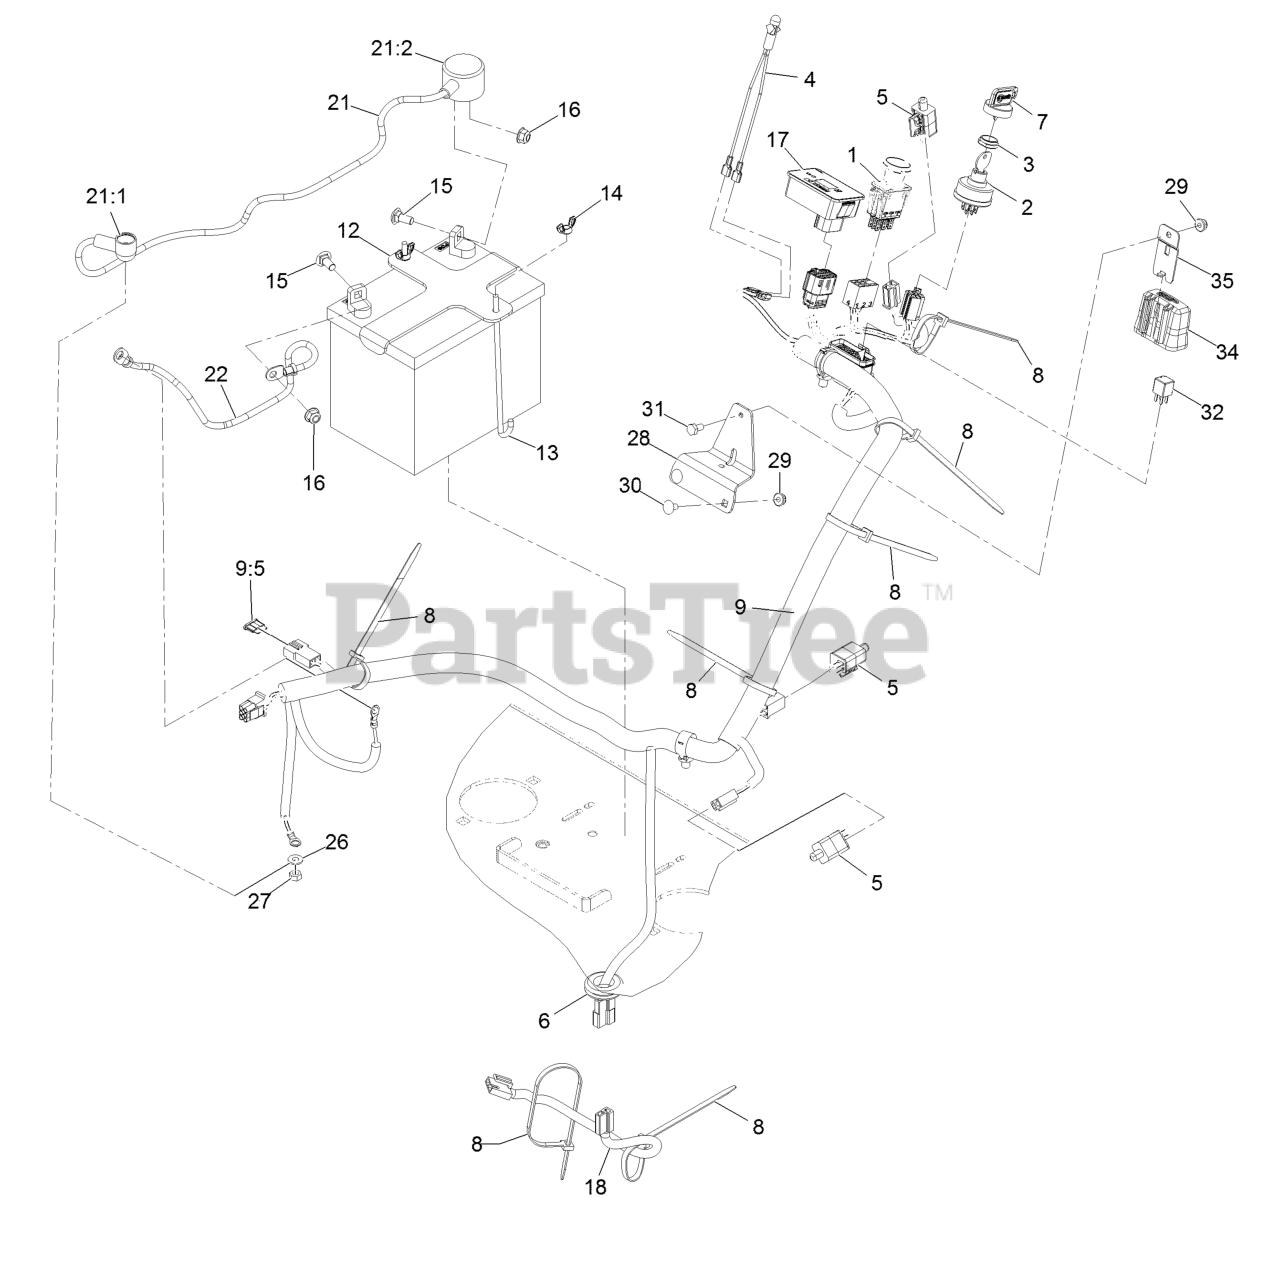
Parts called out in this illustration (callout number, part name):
1	Switch-PTO
2	Switch, Key Start
3	Nut-Ignition
4	Indicator-Red LED
6	Grommet
7	Key-Exmark Logo
8	Tie-Cable 7 15/16 (Large)
9	Harness-Wire
9:5	Fuse-Blade Type, 20 Amp
12	Bracket, Battery Hold Down
13	Bolt-Holddown
14	Wingnut-Nyloc 1/4-20
15	Bolt-Carriage 5/16-18 X 3/4
16	Nut-Nyloc 5/16-18 Flg
17	Module-Hour Meter
18	Harness-Clutch Pigtail
21	Positive Battery Cable ASM
21:1	Insulator-Solenoid
21:2	Insulator-Battery
22	Cable-Battery, Negative
26	Washer-Flat
27	Nut-Hex
28	Bracket-Mounting, Fuseblock
29	Nut-Nyloc 1/4-20 Flg
30	Bolt-Carriage 1/4-20 X 1/2
31	Screw-HH 1/4-20 X 1/2
32	Relay-Micro
34	Cover-Block, Fuse
35	Clip-Mounting
